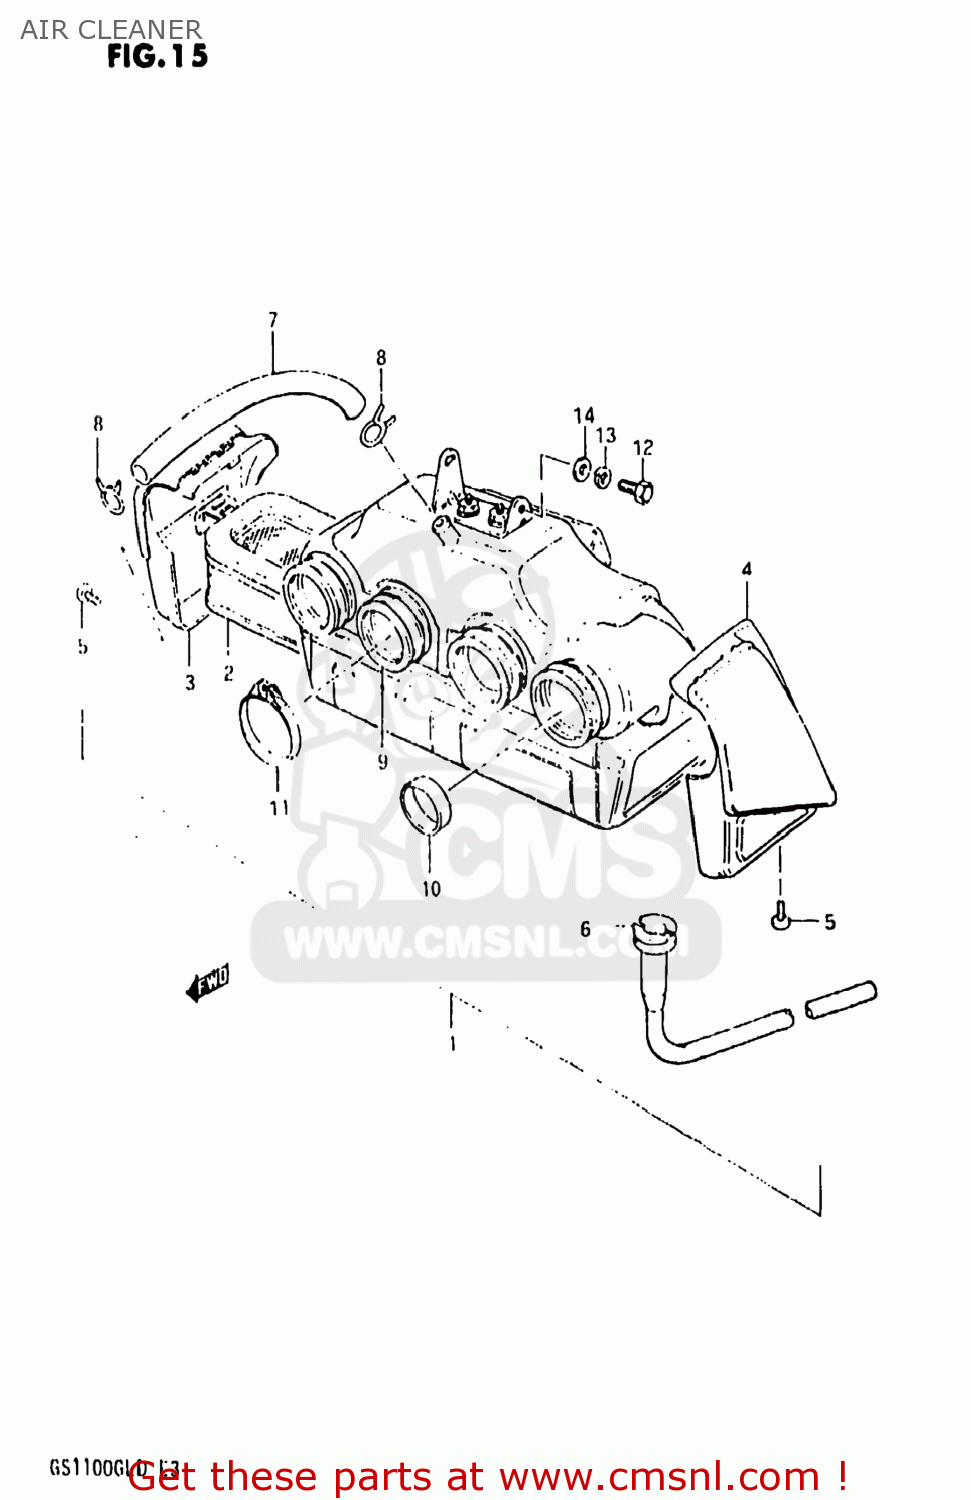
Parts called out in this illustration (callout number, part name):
1	CLEANER ASSEMBLY,AIR
2	FILTER ASSY
3	CAP,AIR CLEANER
4	CAP,AIR CLEANER,LEFT
5	SCREW
6	DRAIN TUBE
7	TUBE,BREATHER
8	CLIP
9	TUBE,OUTLET
10	RING,CARBURETOR AIR IN
11	CLAMP
12	BOLT
13	LOCK WASHER
14	WASHER 6MM
